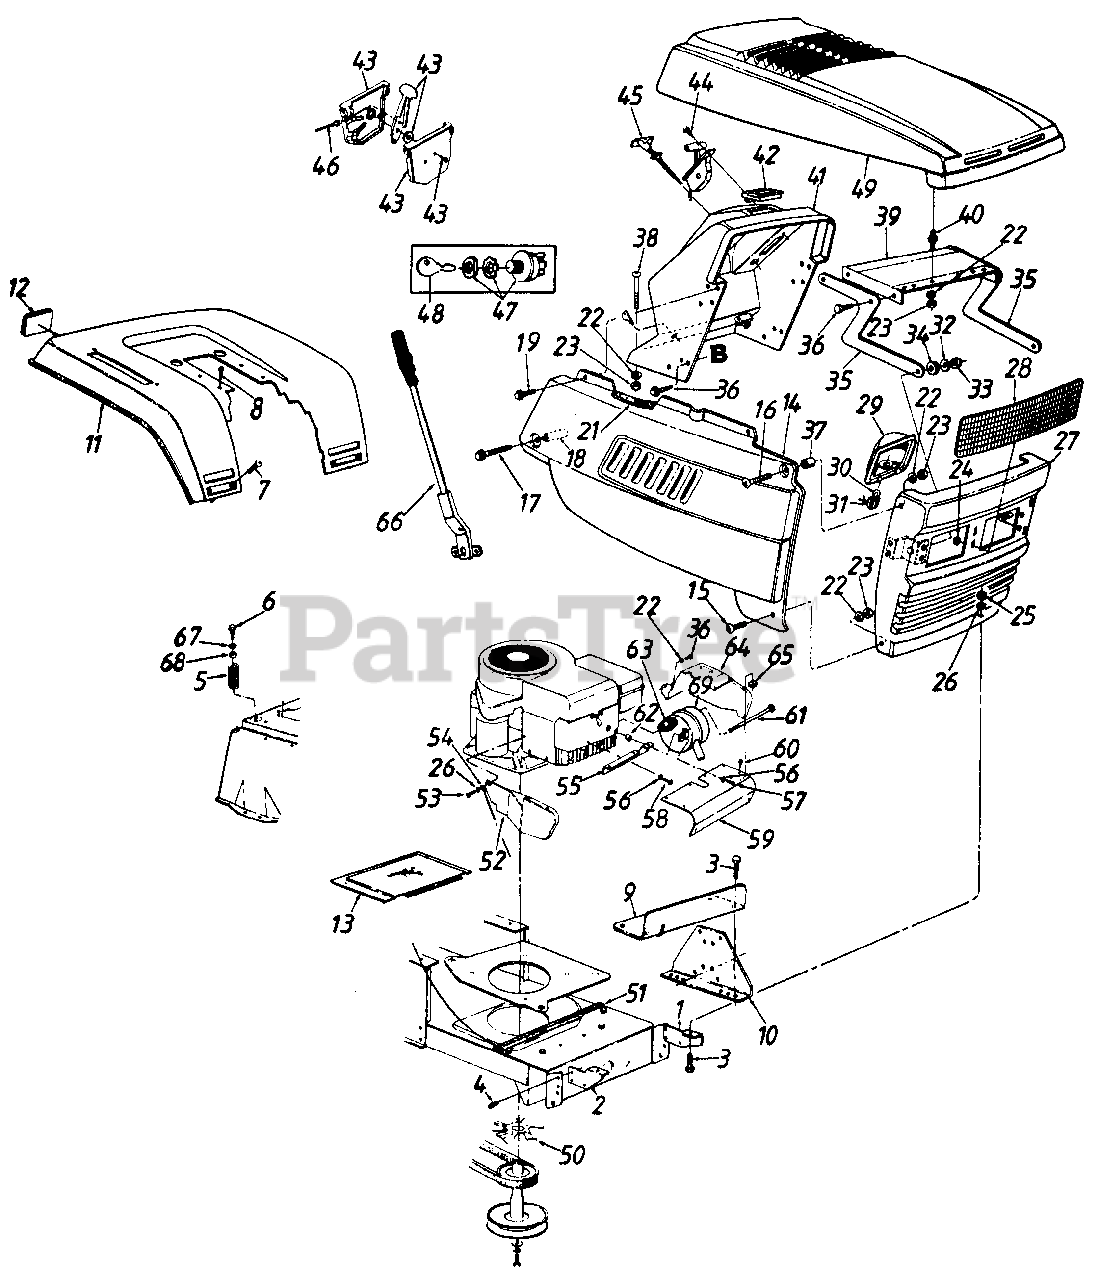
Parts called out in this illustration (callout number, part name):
1	Grille Mtg. Brkt.-L.H.
4	Hex Wash. Hd. Tap Scr. 5/16-18 x .5" Lg.
5	Compression Spring
6	Hex Wash. TT-Tap Scr. 5/16-18 x 1.25" Lg.
7	Carriage Bolt 1/4-20 x .5" Lg.
8	Hex Wash. Hd. Tap Scr. 5/16 x .75" Lg.
9	Fuel Tank Support
10	Dash Support Bracket
13	Transmission Cover
14	Side Panel-R.H.
15	Truss Mach. Scr. 1/4-20 x .5" Lg.
16	Truss Mach. Scr. 1/4-20 x 1.0" Lg.
17	Hex Wash. TT-Tap Scr. 1/4-20 x 1.75" Lg.
18	Spacer .26" I.D. x 1.32
19	Hex Rolling Tap Scr. 1/4 20 x .75" Lg.
21	Trim Strip-6" Lg.
22	L-Wash. 1/4" I.D.
23	Hex Nut 1/4-20 Thd.
24	Speed Nut 5/16" Thd.
25	Hex Nut 5/16-18 Thd.
26	L-Wash. 5/16" I.D.
29	Headlamp Housing
30	Headlamp
31	Twist Lock Lamp Socket
32	Bell-Wash. .345" I.D. x .88"
33	Hex L-Nut 5/16-18 Thd.
34	Rubber Washer
35	Hood Hinge
36	Hex Wash. Hd. B-Tap Scr. 1/4-20 x .5" Lg
37	Spacer .265" I.D. x .376"
38	Truss Mach. Scr. 1/4-20 x 1.5" Lg.
39	Hood Plate
40	Double Ended Stud 1/4-20 Thd.
42	Ammeter
43	Throttle Control Box Ass'y.
44	Truss Mach. AB-Tap Scr. #10 x .5" Lg.
45	Choke Control 29" Lg.
46	Throttle Control Wire
47	Ignition Switch
48	Ignition Key
51	Foam Strip
52	Muffler Heat Shield-R.H.
53	Truss Mach. Scr. 5/16-18 x .75" Lg.
54	Ground Wire
55	Heat Shield Bracket
56	Spr. Wash. 1/4" I.D.
57	Hex Bolt 1/4-20 x .85" Lg.
58	Hex Bolt 1/4-20 x 3/8" Lg.
59	Muffler Heat Shield-Front
60	Hex AB-Tap Scr. #10 x .5" Lg.
61	Shoulder Bolt
62	Spacer
63	Exhaust Gasket
64	Muffler Heat Shield-L.H.
65	Speed Nut #10-24 Thd.
66	Lift Handle
67	Fl-Wash. .344" I.D. x .875"
68	Bushing
69	Muffler
